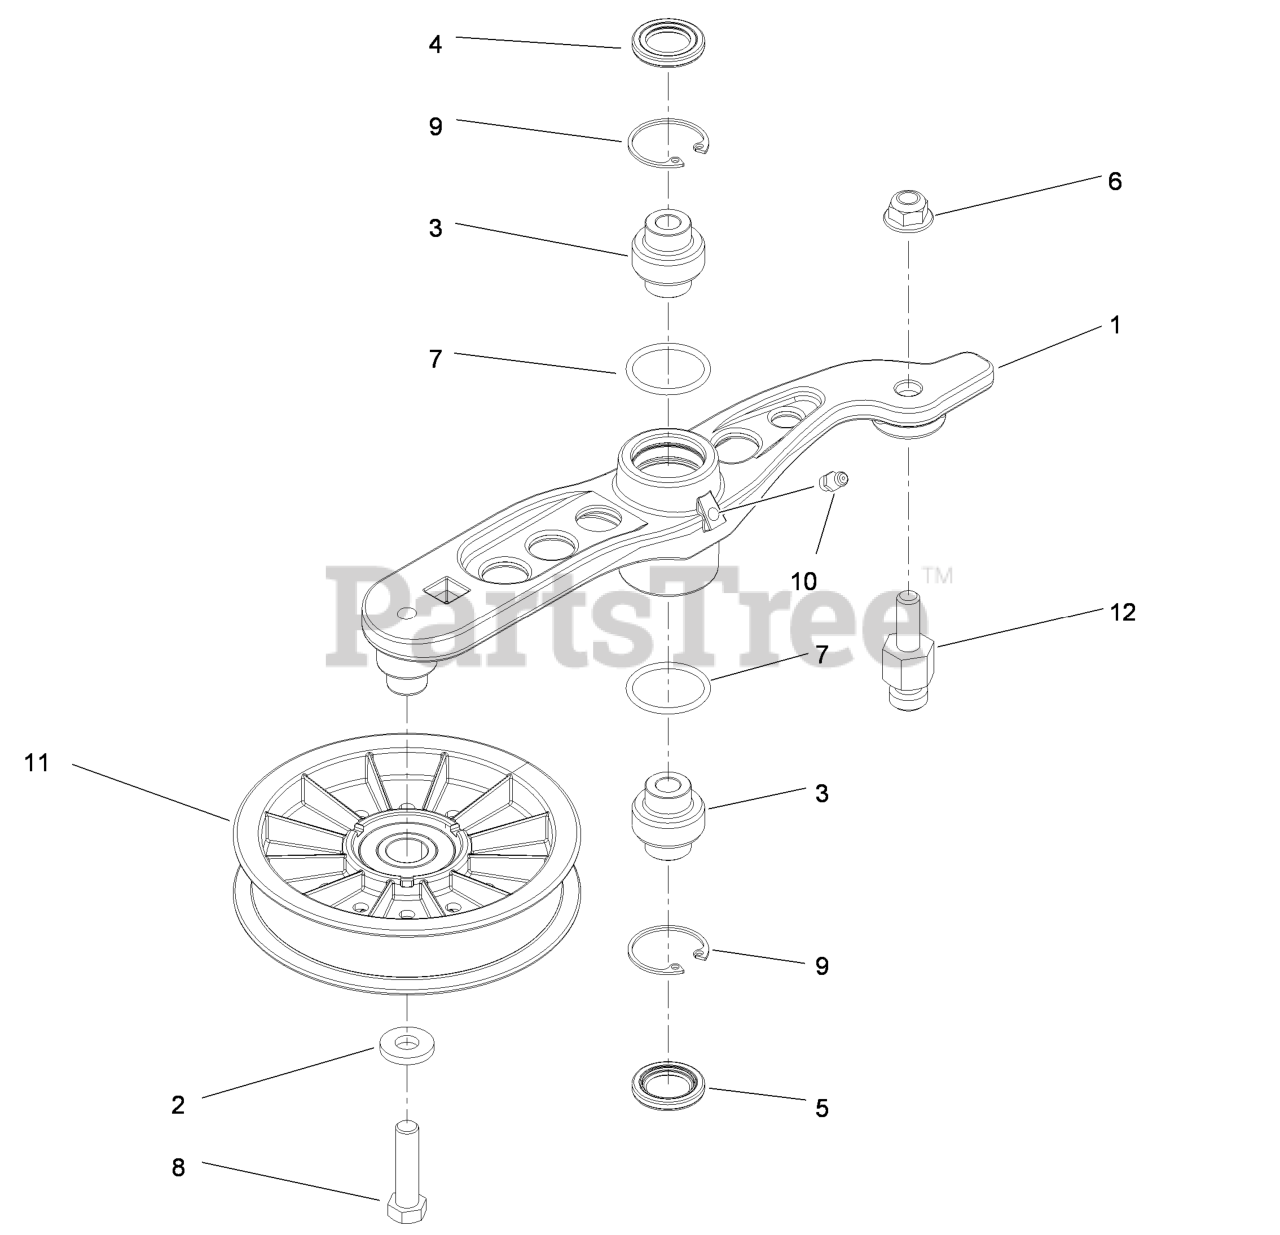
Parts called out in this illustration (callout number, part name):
1	Arm-Pump, Idler
3	BEARING-SPHERICAL
4	SEAL-LIP, DOUBLE
5	SEAL-LIP, SINGLE
6	Nut-Nyloc 3/8-16 Flg
8	SCREW-HH
9	RING-SNAP
10	FITTING-GREASE
11	PULLEY-IDLER
